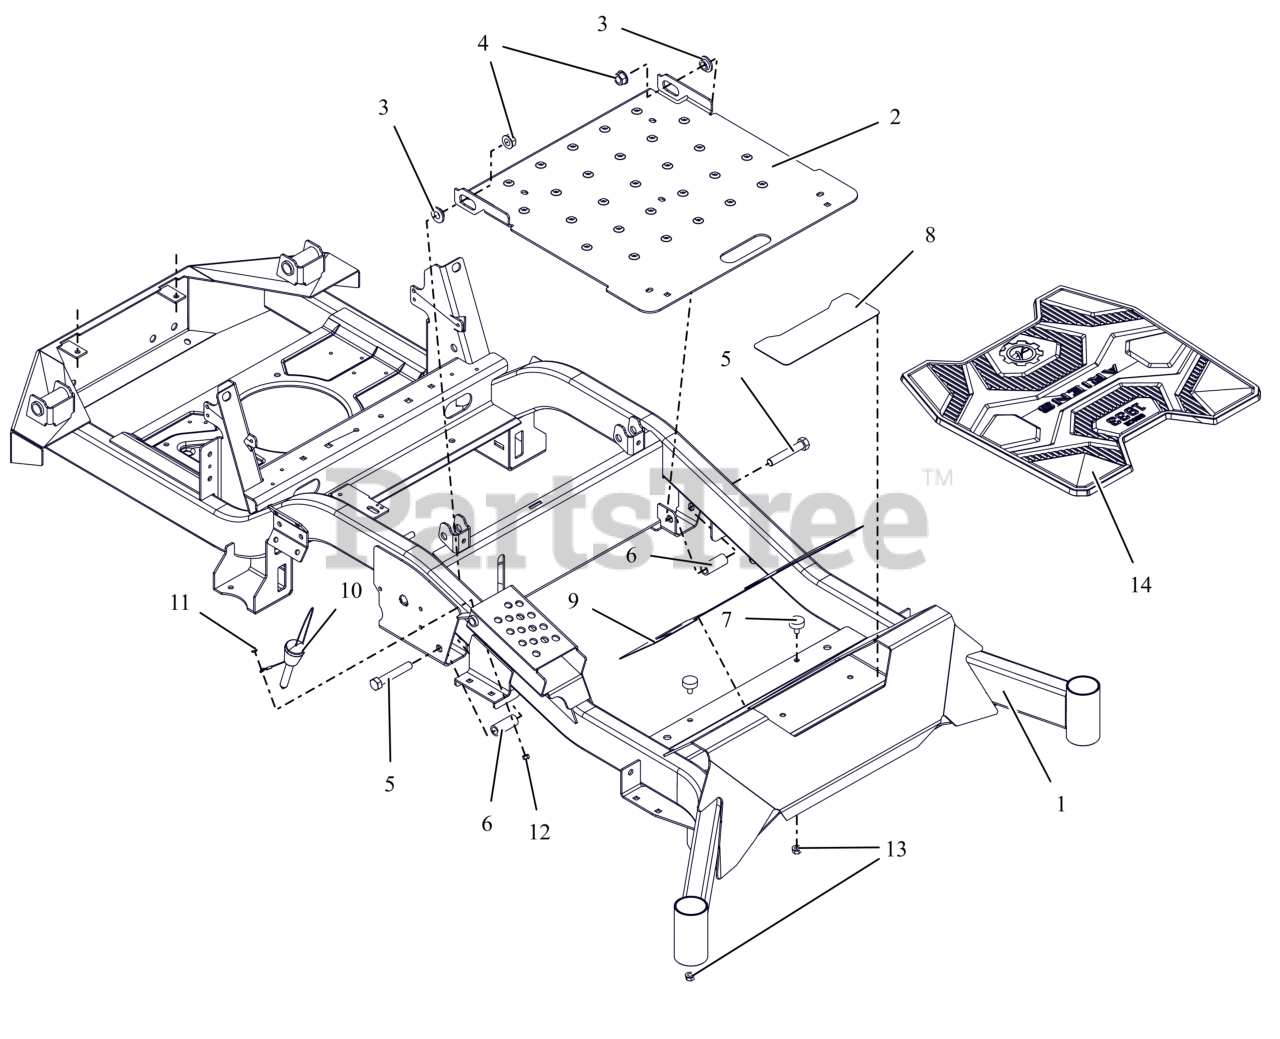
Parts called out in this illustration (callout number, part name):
1	APEX LE 60" FRAME W/DECALS
2	KIT,ACCESS PANEL W/DECALS-GRY
3	BSHG-FLG .515X.750X.395X1.120
4	NUT-LK-TOP-FLG .500-13 GF ZCC
5	BLT, HEX .50-13X3.00 G5 ZCC
6	SPACER, .515X.75X1.83
7	BUMPER, RUBBER
8	GRIP, STEP
9	GRIP, FRONT
10	PIN- MAGNETIC .50X2.70
11	POST, & SCREW, PUSH LOCK .25 X .25
12	NUT-LK-NYL #10-24 G2 ZCC
13	NUT,SPNLK-FLG .31-18 G5 ZCC
14	FLOOR MAT- RUBBER ARIENS
